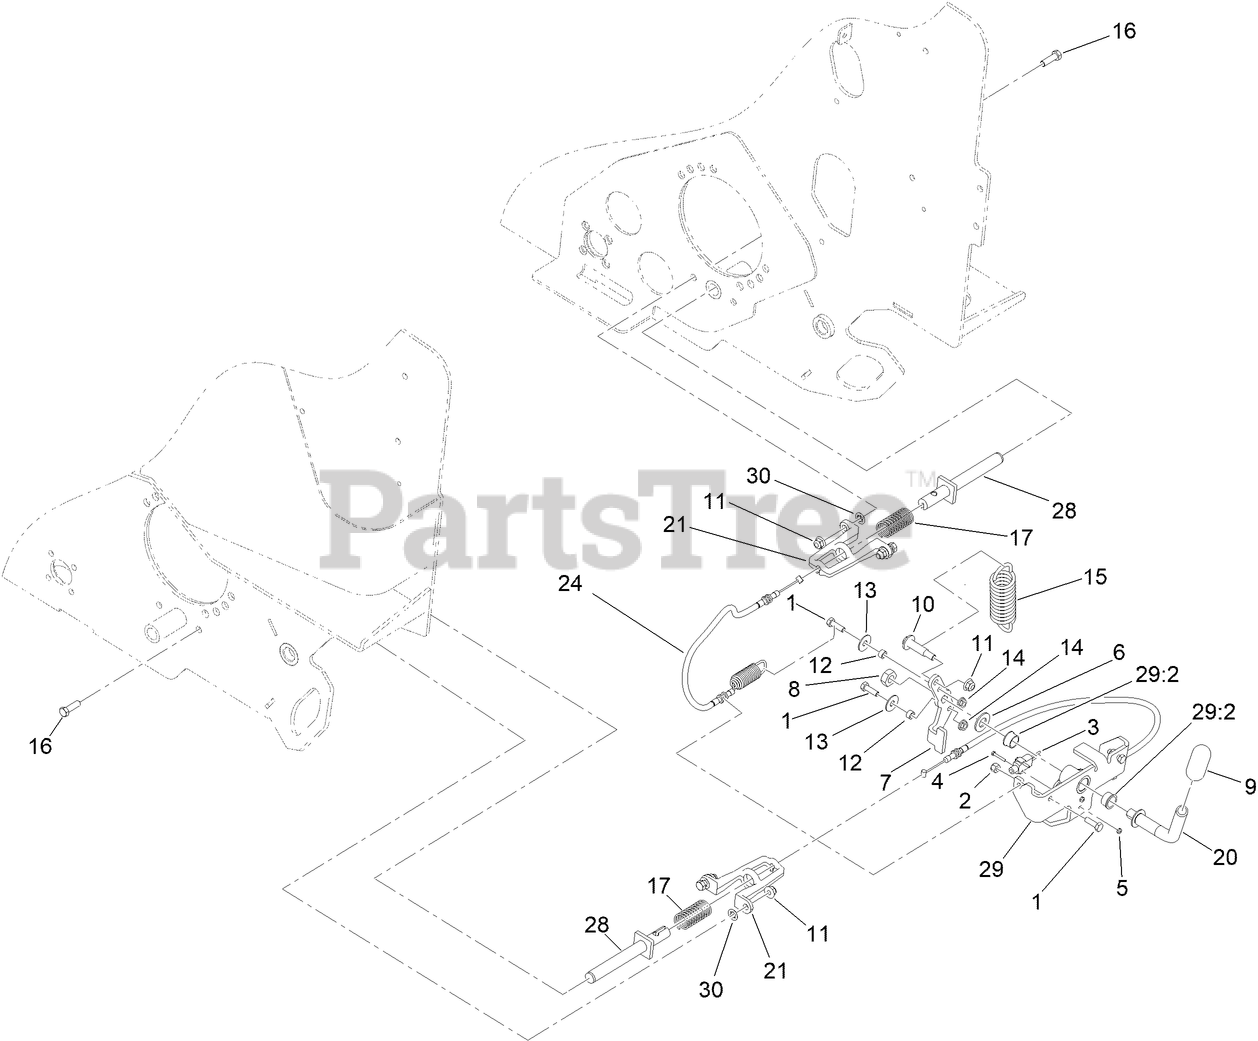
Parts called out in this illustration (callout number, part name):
1	SCREW-HH
2	NUT-LOCK, NI
3	SWITCH
4	SCREW
5	NUT-HEX
6	WASHER-FLAT
7	PLATE-BRAKE LINKAGE
8	NUT-LOCK, NI
9	GRIP-HANDLE
10	BOLT-SHOULDER
11	NUT-HF, NI
12	SPACER-PIVOT, TILT
13	WASHER
14	NUT-HF
15	SPRING-EXT
16	SCREW-HH
17	SPRING-COMPRESSION
20	LEVER-BRAKE
21	MOUNT-PIN [BLACK]
24	CABLE-BRAKE
28	BRAKE ROD ASM
29	BRAKE BRACKET ASM
29:2	BEARING-FLANGE
30	NUT-PUSH
